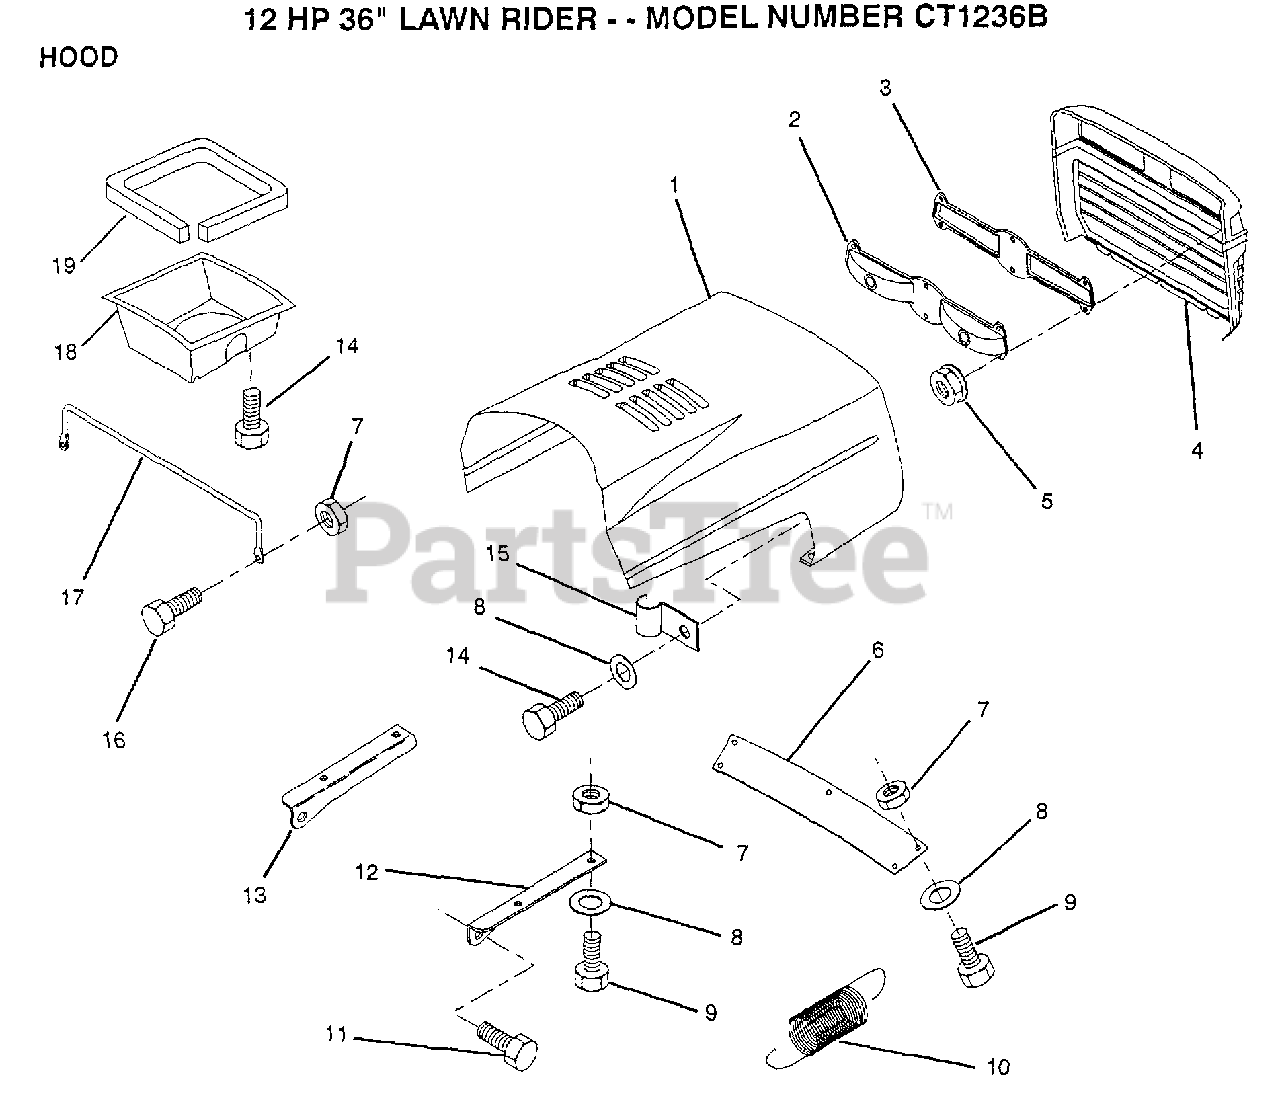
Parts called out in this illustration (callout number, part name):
1	No Desciption for Part
5	NUT
6	"STRAP,GRILL T"
7	NUT
8	WASHER
9	BOLT
10	EXT SPRING
12	BRKT HOOD RH
13	BRKT HOOD LH
15	CLIP T
17	"BRACE,HOOD"
18	"DUCT,AIR"
19	FOAM STRIP LT
